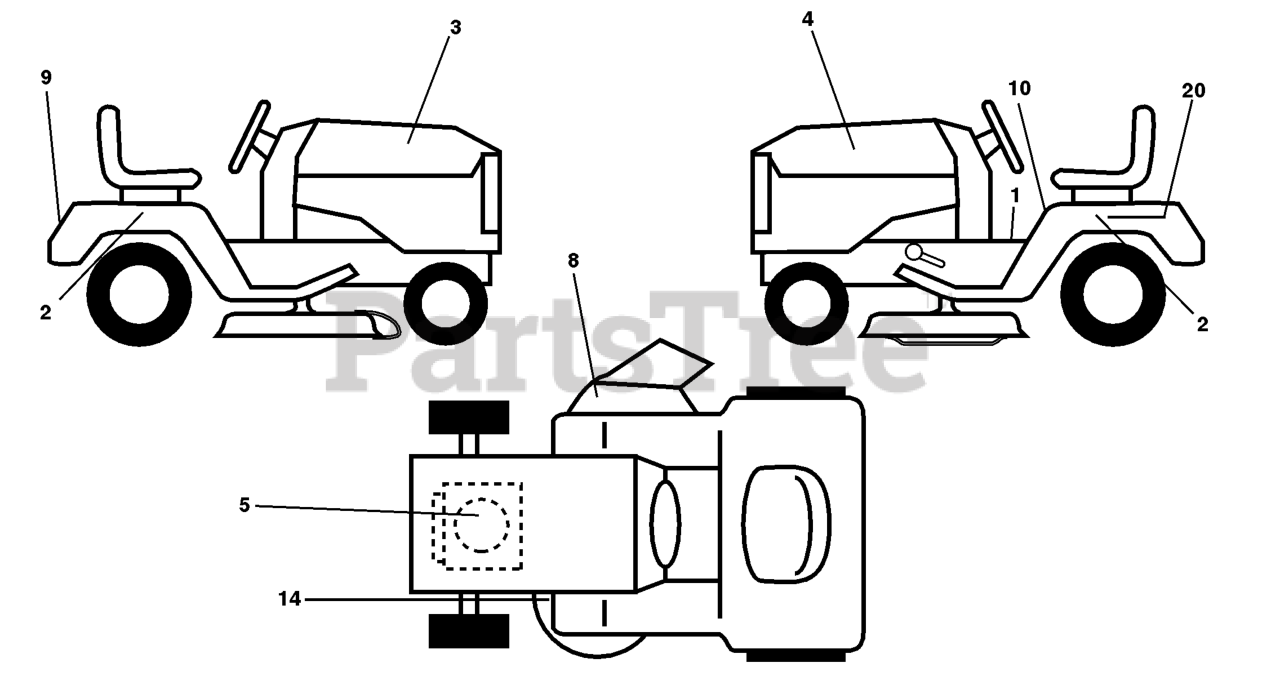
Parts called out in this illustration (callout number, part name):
3	DECAL, HOOD RH LTH120
4	DECAL, HOOD LH LTH120
5	DECAL-ENGINE HP
8	DECAL WARNING (ENGLISH/FRENCH)
9	DECAL FENDER HUSQ
10	DECAL FENDER DANGER
14	DECAL V-BELT SCHEMATIC
20	DECAL BTRY SYMBOLS
